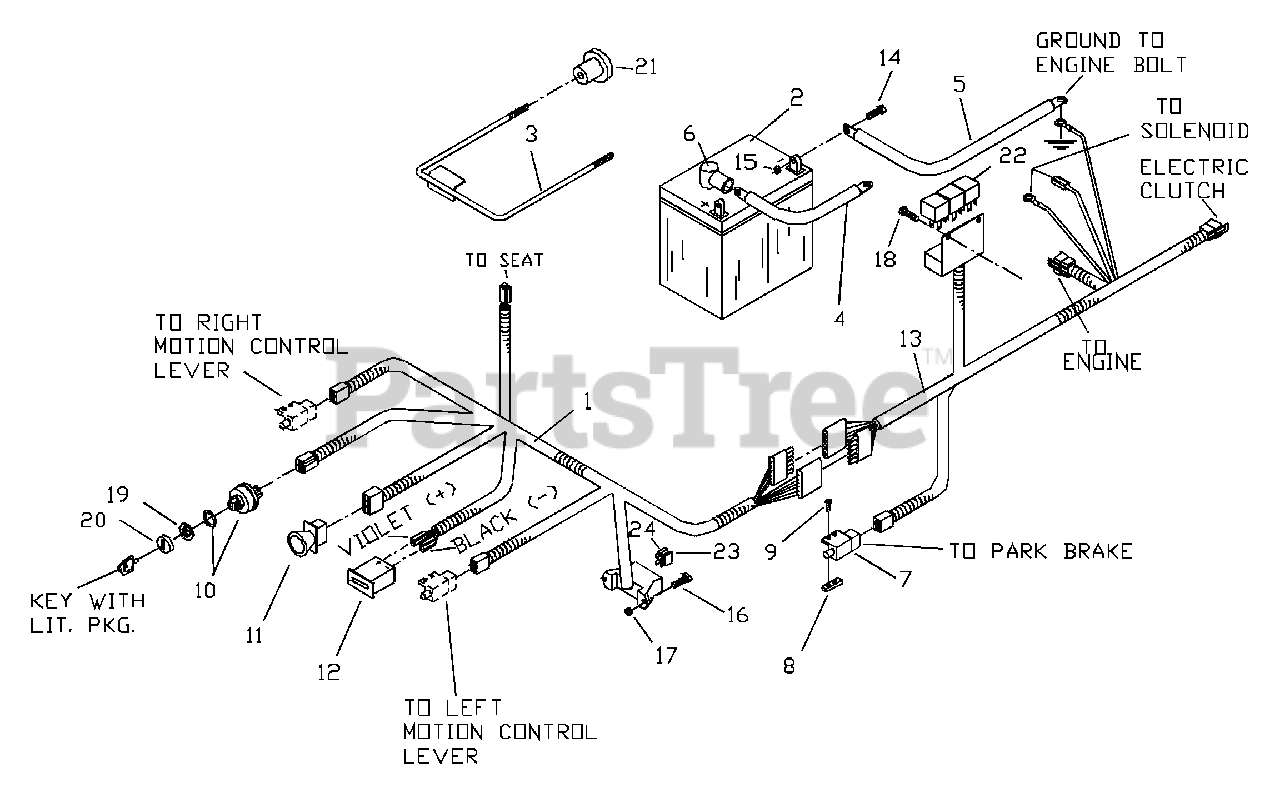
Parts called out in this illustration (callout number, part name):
1	CONSOLE HARNESS
2	12V BATTERY
3	BATTERY HOLD DOWN
4	POSITIVE CABLE
5	NEGATIVE CABLE
7	INTERLOCK SWITCH
8	TAPPED PLATE
9	#10-24 X 5/8
10	IGNITION SWITCH
11	BLADE SWITCH
12	HOUR METER
13	FRAME HARNESS
14	HCS 5/16C X 3/4
15	NUT 5/16C CTR. LOCK
16	#10-24 X 7/8 SCREW
17	#10-24 HEX NYLOC NUT
18	SELF TAPPING SCREW
19	NUT IGN. SWITCH
20	CAP, IGN. SWITCH
23	7.5AMP 32V ATO FUSE
24	20.0AMP 32V ATO FUSE
